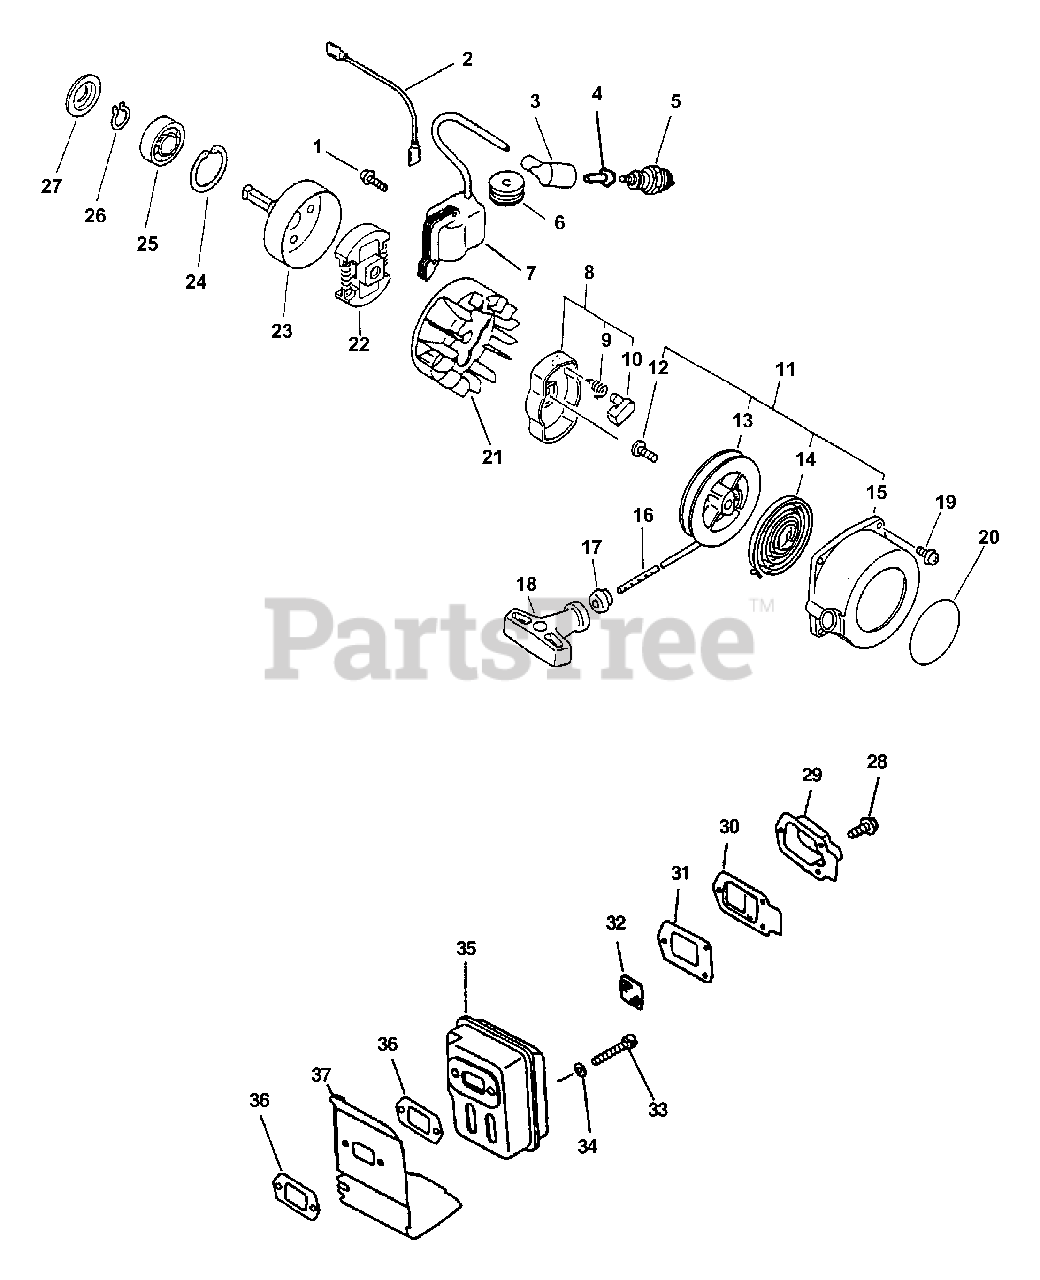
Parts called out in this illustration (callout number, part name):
1	SCREW - 4X22
2	LEAD - IGNITION
3	CAP, SPARK PLUG
4	TERMINAL, SPARK PLUG CAP
5	SPARK PLUG -- BPM-7A
5	SPARK PLUG -- BPMR-7A
6	GROMMET
7	COIL, IGNITION
8	STARTER PAWL ASSY
9	SPRING, RETURN
10	PAWL, STARTER - BLACK
11	STARTER ASSY
13	REEL, ROPE
14	SPRING, REWIND
15	CASE, STARTER
16	ROPE, STARTER - 3X1000
17	GUIDE, ROPE
18	GRIP, STARTER
19	SCREW - 4X16
20	LABEL - ECHO
21	FLYWHEEL
22	CLUTCH ASSY
23	DRUM, CLUTCH
24	RING, RETAINING - 32
25	BEARING, BALL - 6201
26	RING, RETAINING - 12
27	RETAINER, PIPE
28	SCREW - 4X10
29	GUIDE, EXHAUST - OUTER
30	GASKET, EXHAUST - INNER
31	GASKET, EXHAUST
32	SCREEN, SPARK ARRESTOR
33	SCREW - 5X55
34	WASHER - 5
36	GASKET, EXHAUST
37	SHIELD, EXHAUST
